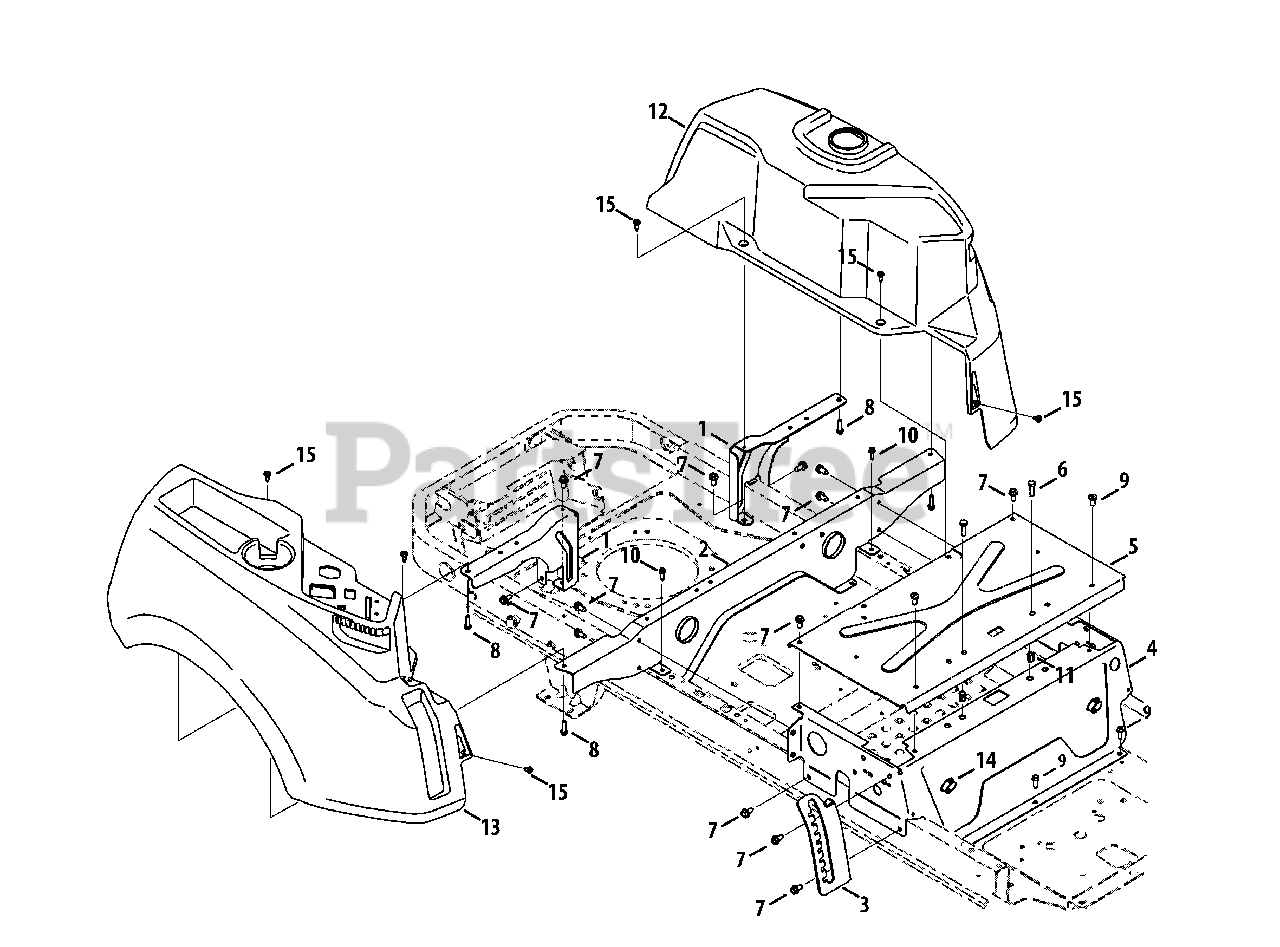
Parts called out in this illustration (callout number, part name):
1	Rear Tank Bracket
2	Rear Seatbox Brace
3	Height Index Bracket
5	Seatbox Plate
6	Hex Cap Screw, 5/16-18 x 1.00
7	Hex Washer Screw, 5/16-18 x .750
8	Hex Washer Screw, 5/16-14 x 1.00
9	Self Tapping Screw, 5/16-18 x .750
10	Hex Washer Screw, 5/16-18 x .50
11	Nut, 5/16-18
12	LJ Console
13	RH Console
14	Plastic Plug
15	Shoulder Screw, 1/4-20
